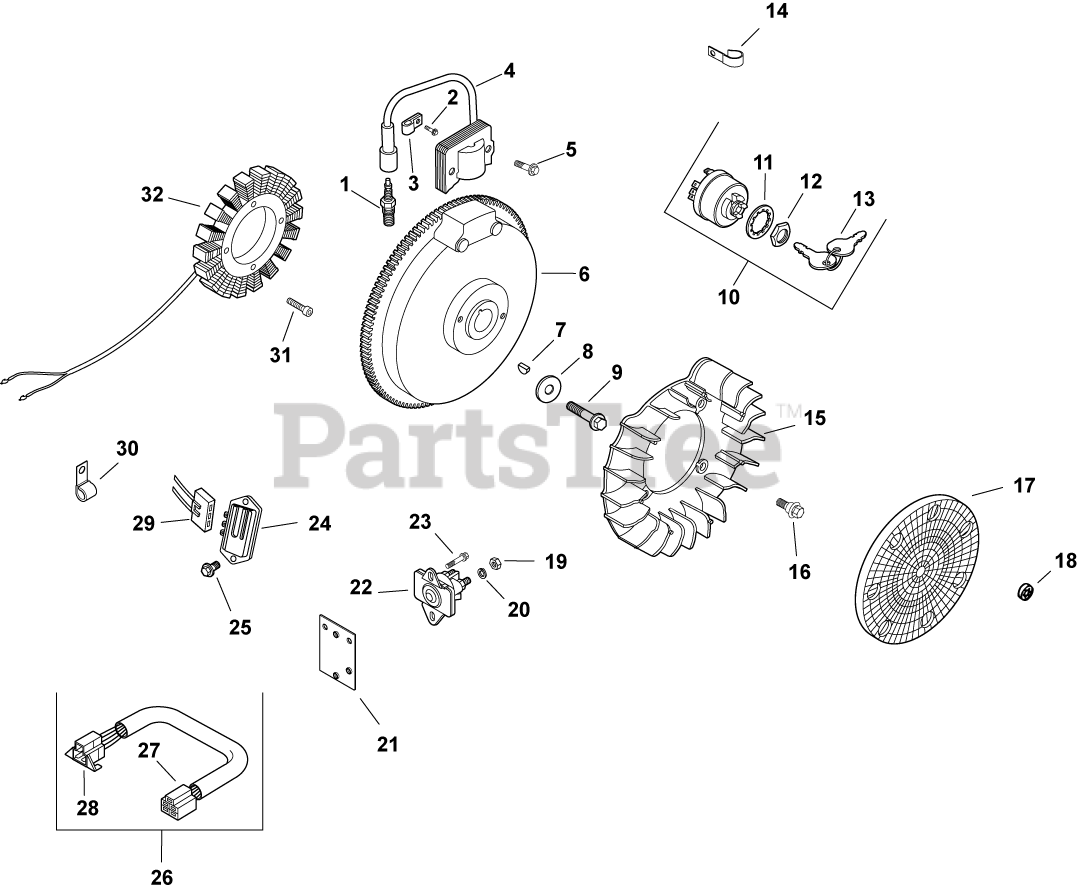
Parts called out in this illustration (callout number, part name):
1	SPARK PLUG
2	SCREW, FLG THD FRM M5X.8X10
4	MODULE, IGNITION
5	SCREW, FLG THD FRM M5X.8X20-(#25086399S)
6	FLYWHEEL - USE 12 025 16-S
7	KEY, 3/16" X 5/8"
8	WASHER, FLAT 13/32"
9	SCREW, FLG M10X1.5X45 - (#25086361S)
10	SWITCH ASSY, KEY (KM)-USE 25 099 32-S
11	WASHER, INTERNAL TOOTH
12	NUT, KEY SWITCH
13	KEY, SET -USE 48 340 01-S
14	CLIP, CABLE
16	BOLT, SHOULDER
17	SCREEN, GRASS
19	WASHER, INT TOOTH LOCK 1/4"
20	NUT, JAM 1/4-20 GRADE 2
21	BRACKET, CRANKING RELAY
22	SOLENOID - WATERPROOF (KM)-USE 25 435 08
23	SCREW,FLG THD FRM M6X1.0X16-(#25086397S)
24	REG/RECT-15 AMP (KM)-USE 41 403 10-S
25	SCREW, FLG M6X1.0X16
26	CONNECTOR ASSEMBLY
27	CONNECTOR
28	CONNECTOR
29	CONNECTOR, BODY (KM)-USE 25 155 41-S
30	CLIP, CABLE
31	SCREW, M5X0.8X25 - (#25086402S)
32	KIT, 15 / 20 AMP STATOR
